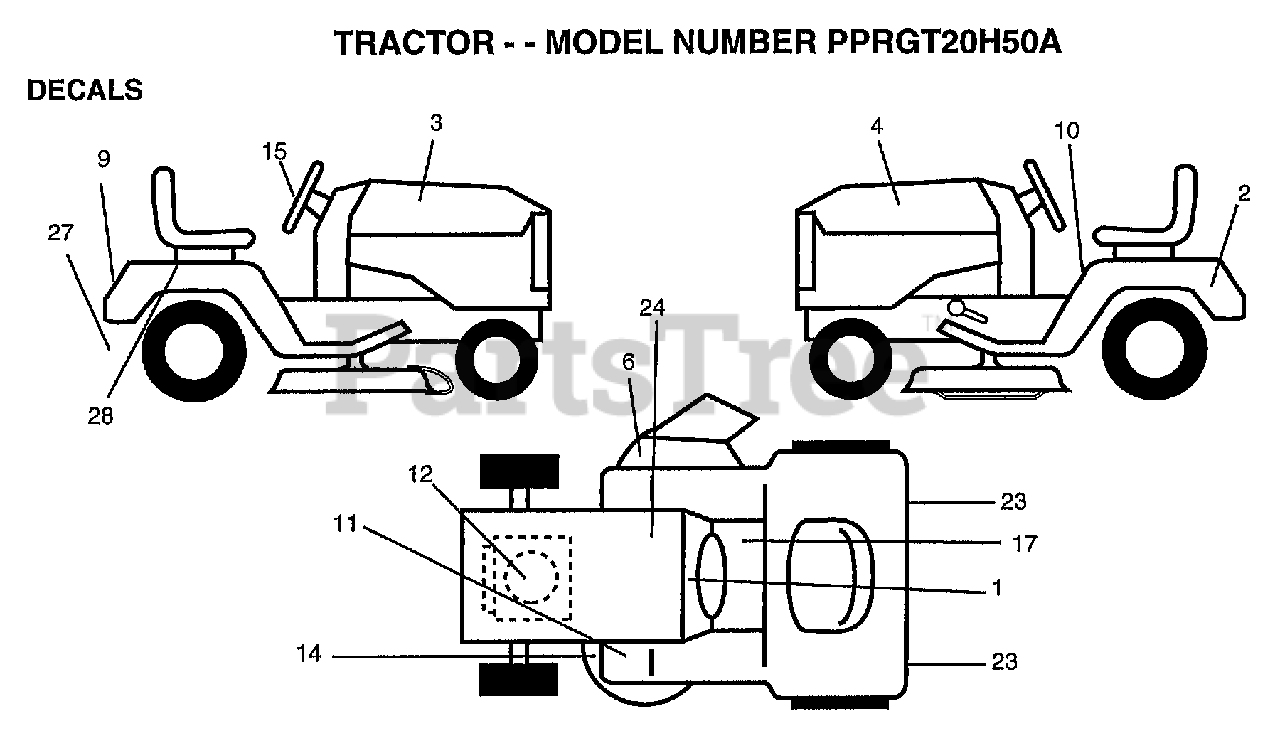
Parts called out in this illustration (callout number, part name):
1	DECAL OPER INSTR.
2	DECAL.FENDER.SD.AUTO
3	DECAL.HOOD.RH
4	DECAL.HOOD.LH
5	DECAL.DASH
6	"DECAL, WARNING"
9	DECAL.FENDER.LOGO
10	DECAL.CAUT.ENG/FR
11	DECAL T
12	DECAL KOHLER 20 OHP DMD
15	DECAL.INS.WHL.STRG
17	DECAL BRAK PARK
23	REFLECTOR-TAIL YT
24	DECAL.BATRY.3-3908
27	DECAL D-BAR CNTRL
28	DECAL.FENDER.SD.RH.
